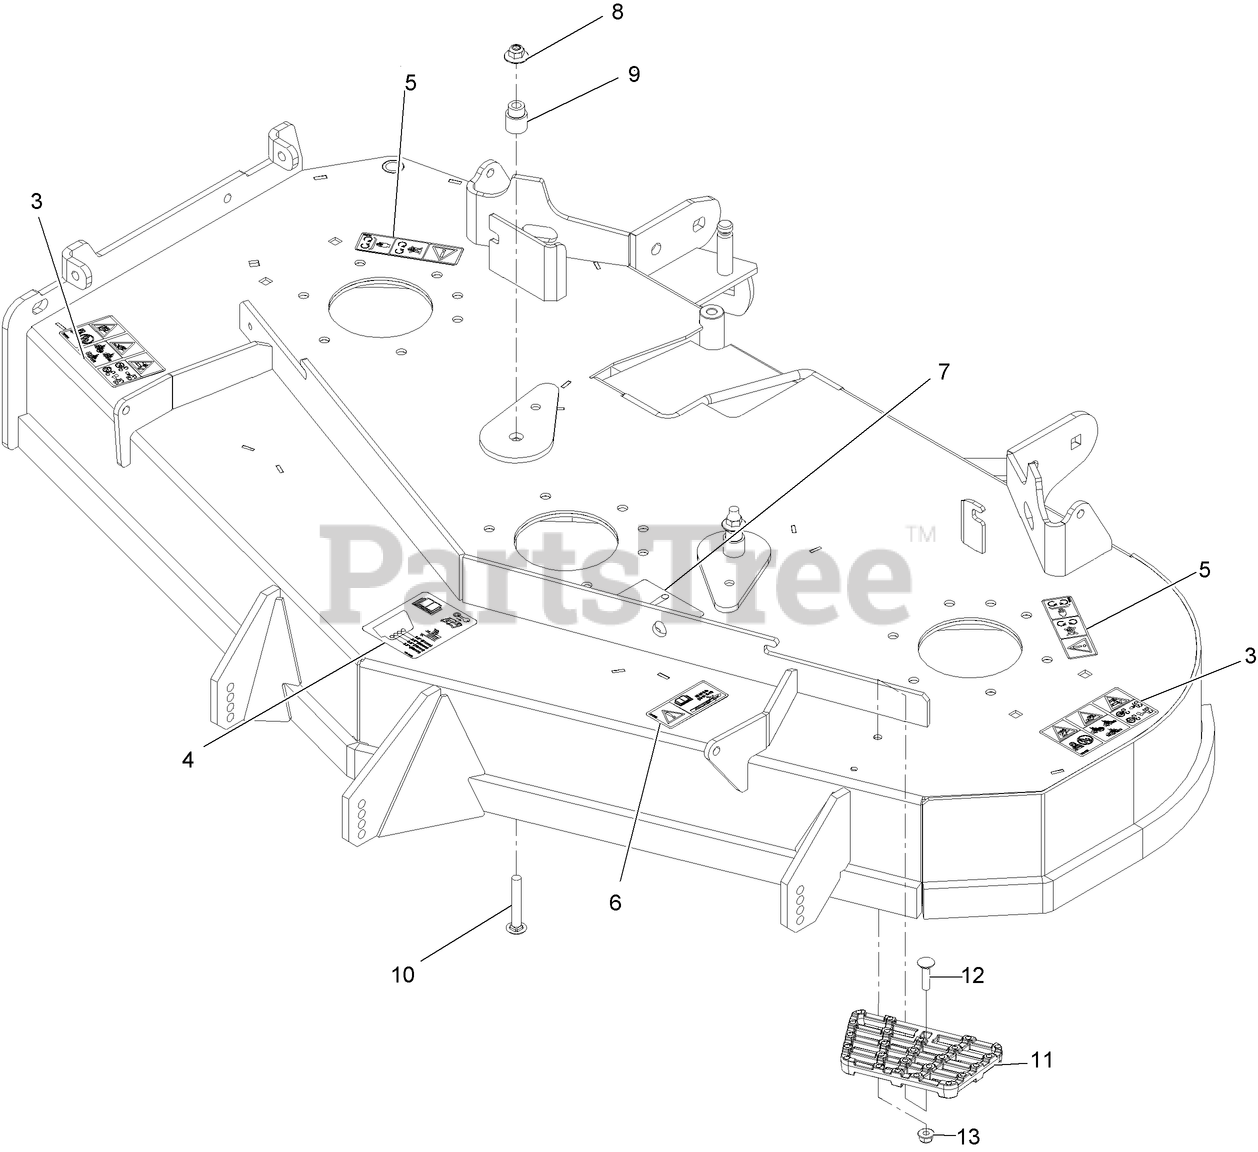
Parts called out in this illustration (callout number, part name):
3	DECAL-DANGER THROWN OBJECTS
4	DECAL-ROLLER, ANTI-SCALP
5	DECAL-COVER, MISSING
6	DECAL-TORQUE, BOLT
7	DECAL-BELT ROUTING
8	Nut-Nyloc 3/8-16 Flg
9	BUSHING-IDLER
10	SCREW-CARR
11	STEP-DECK
12	Bolt-Carriage 5/16-18 X 1 1/4
13	NUT-HF, NI
